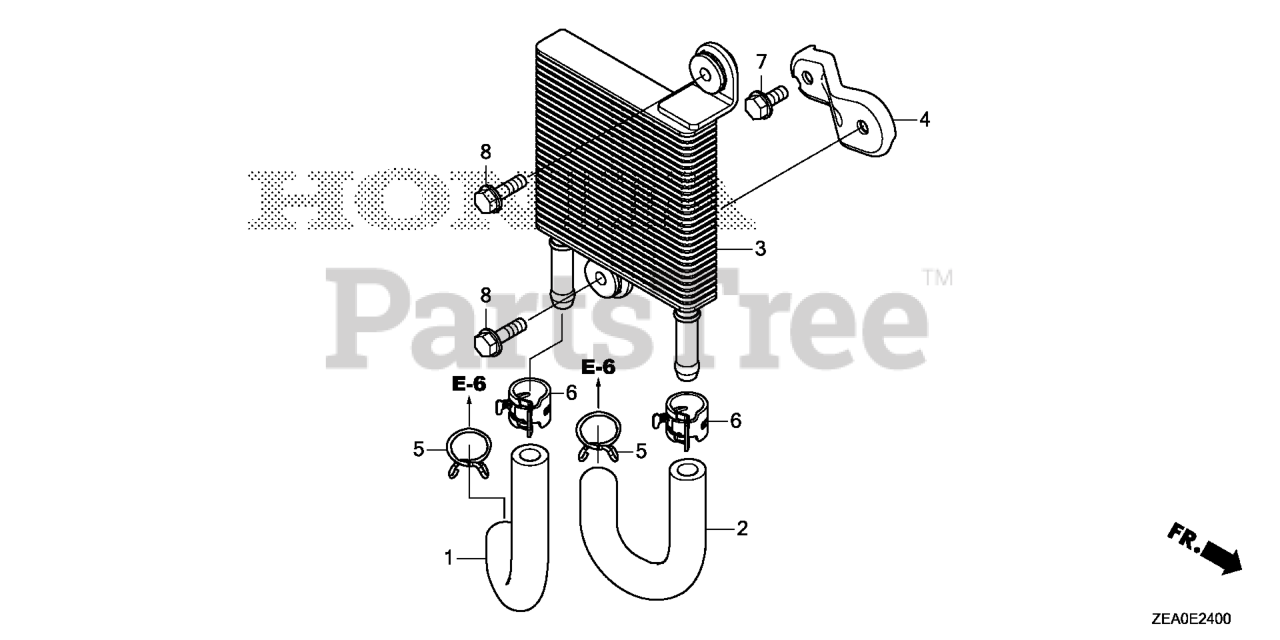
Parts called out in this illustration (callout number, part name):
1	HOSE A, OIL
2	HOSE B, OIL
3	COOLER ASSY., OIL
4	STAY, OIL COOLER
5	CLIP, BREATHER TUBE
6	CLIP, OIL PIPE
7	BOLT, FLANGE (6X14)
8	BOLT, FLANGE (6X20)
